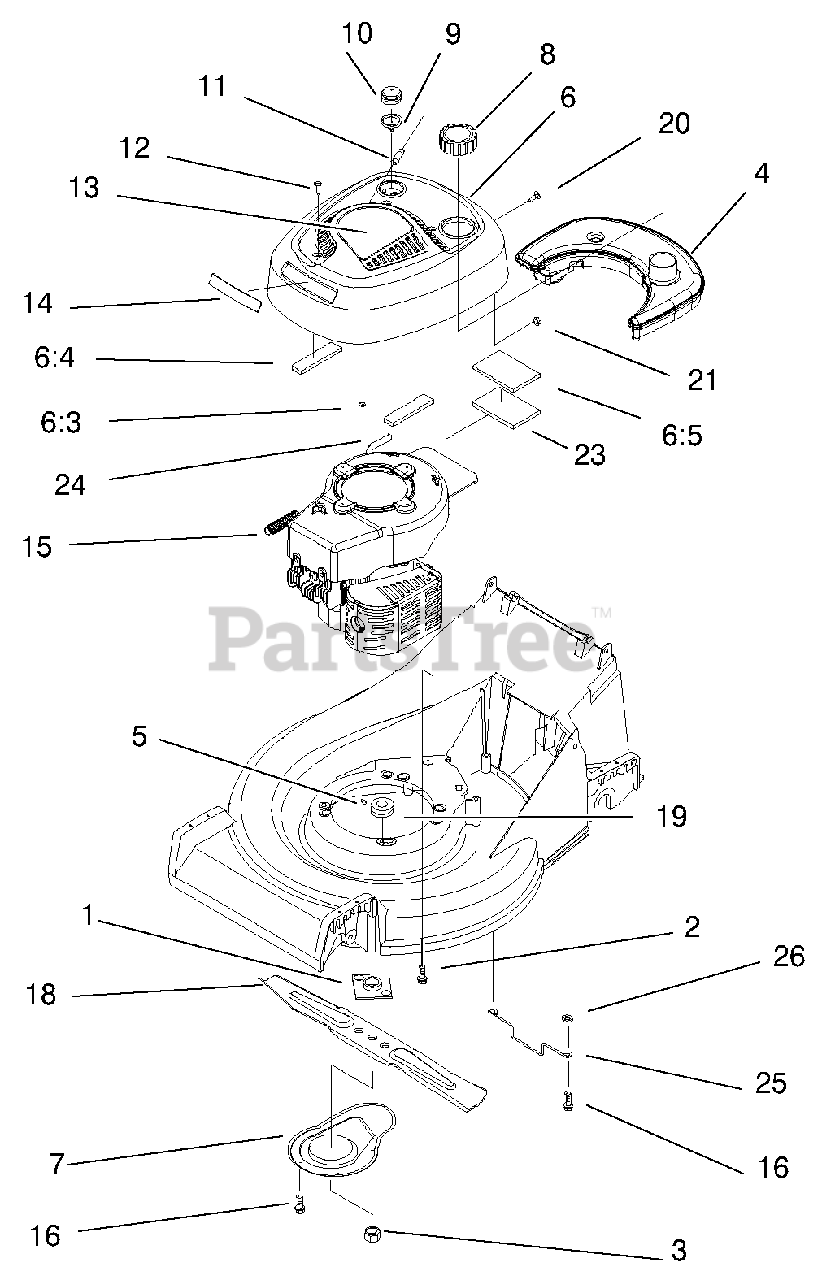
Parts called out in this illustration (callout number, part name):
1	Plate & Collar ASM
2	Screw-Sems
3	Nut-Blade
5	Screw-Set,Cone Point
6	Shroud & Recoil Cover ASM
6:3	Push Nut
6:4	Strip-Foam
6:5	Strip-Foam
8	Cap ASM-Fuel & Oil
9	Body-Primer
10	Bulb-Primer
11	Stop-Rope
12	Screw-Pan Sems
13	Decal-Recoil
14	Decal-Shroud
15	Spring-Compression
18	Blade
21	Nut-Hex
23	Pad-Foam
24	Fuel Line
25	Guide-Belt,Engine
26	Washer-Flat
